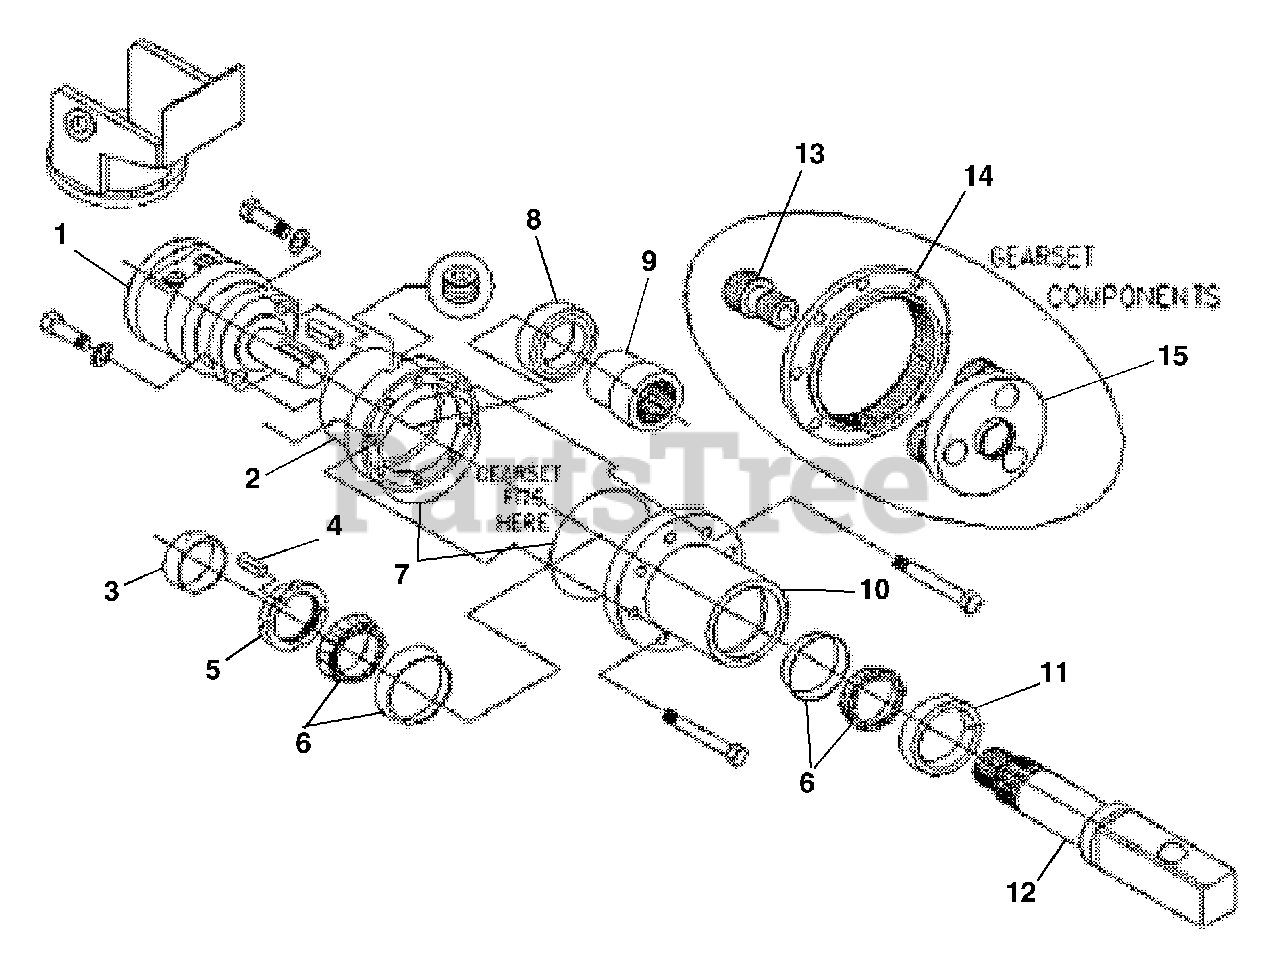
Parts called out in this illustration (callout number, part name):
1	Motor, Hydraulic
2	Housing, Input
3	Ring, Spacer
4	Key, Locking
5	Nut, Locking
6	Bearing, Tapered Thrust
8	Bearing, Input
9	Adapter, Input
10	Housing, Output
11	Seal,Oil
12	Shaft, Output
13	Gear, Input Pinion
14	Gear, Ring
